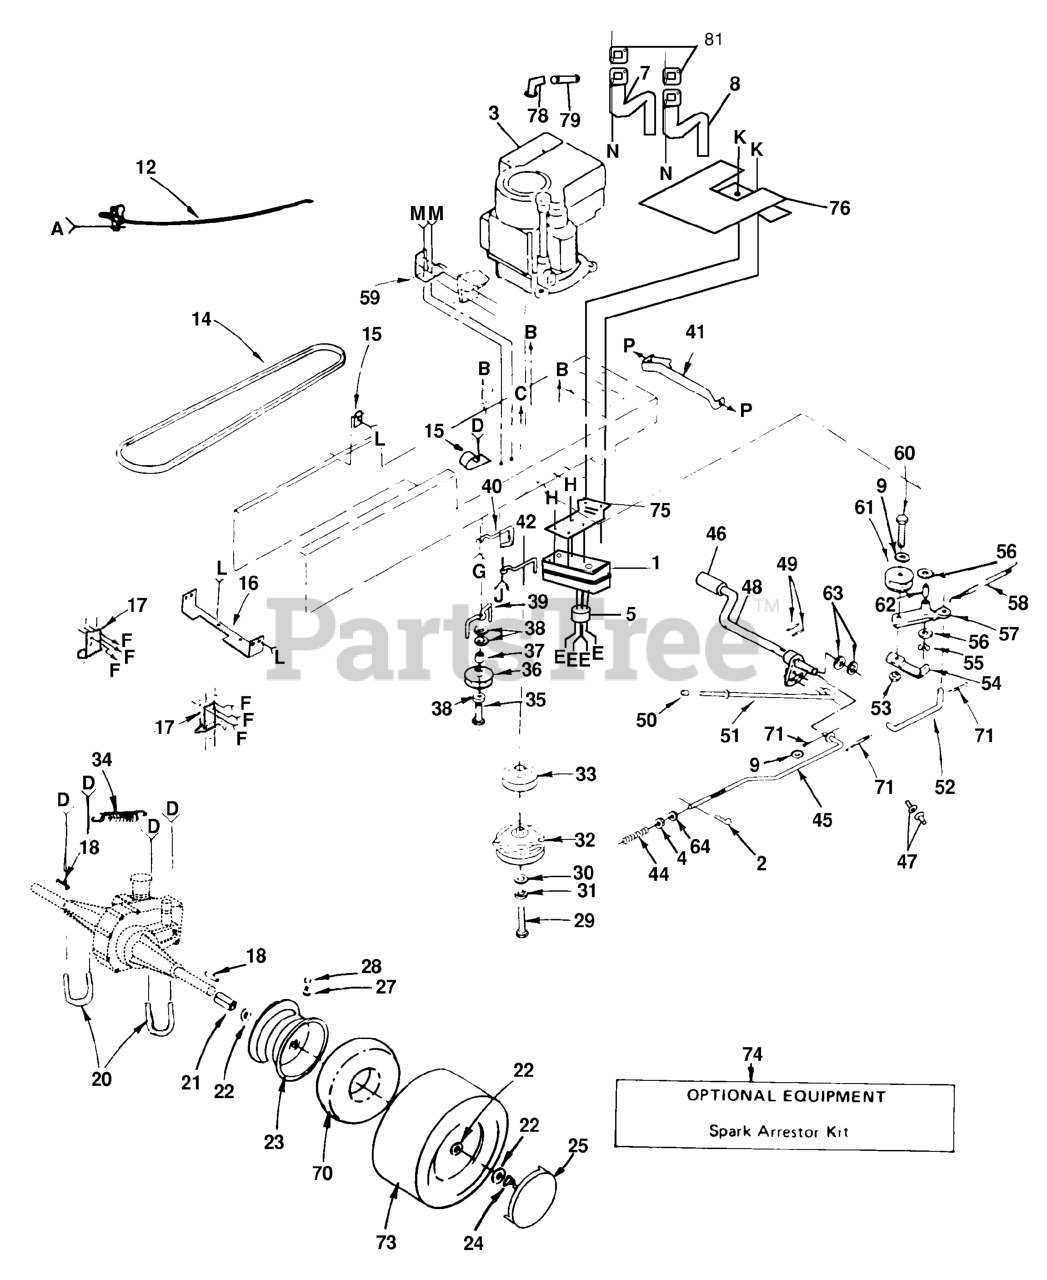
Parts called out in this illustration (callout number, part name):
2	RETAINER M
3	DEFL MUFFLER LTV
4	NUT
5	DEFL MUFFLER LTV
7	TUBE ASSY EXH LH
8	TUBE ASSY EXH RH
9	WASHER
12	CONT THROT CHOKE
15	CLIP T
16	BRKT,MTG NLA
17	BRKT TRANSAXLE
18	SQUARE KEY
21	SPACER SPLIT
23	RIM**
25	CAP,HUB REAR
27	VALVE STEM LT
29	Bolt, Hex, Fin 7/16-20 UNF x 4 Grade 8
31	LOCKWASHER
32	CLUTCH ELEC HYT
33	ENGINE PULLEY
34	SPRING T
36	FLAT IDLER PULLEY
37	SPACER T
38	WASHER
39	BELT KEEPER LT NLA
40	KEEPER BELT ENGLH
41	KIT RETAINER YTH
42	KEEPER,BLT ENG LT
44	SPRING ROD LT
45	ROD BRAKE
46	COVER, PEDAL (1 2)
47	BEARING.NYLON
48	SHAFT FOOT PEDAL
49	PIN.ROLL.3/16 X 1"
50	CAP
51	ROD BRAKE PARK
52	LINK, CLUTCH LT
54	RETAIN BELT
57	ARM IDLER
58	SPRING, RETURN LT
59	BRACKET LT
60	BOLT
61	IDLER PULLEY
62	BEARING LT (2 2)
63	WASHER LT
64	NUT
70	TUBE
71	COTTER PIN
73	TIRE HEAVY DUTY
74	SPARK ARREST
75	BRACKET MUFFLER
76	HEAT SHIELD
78	ELBOW
79	Nipple, Pipe
81	Gasket
